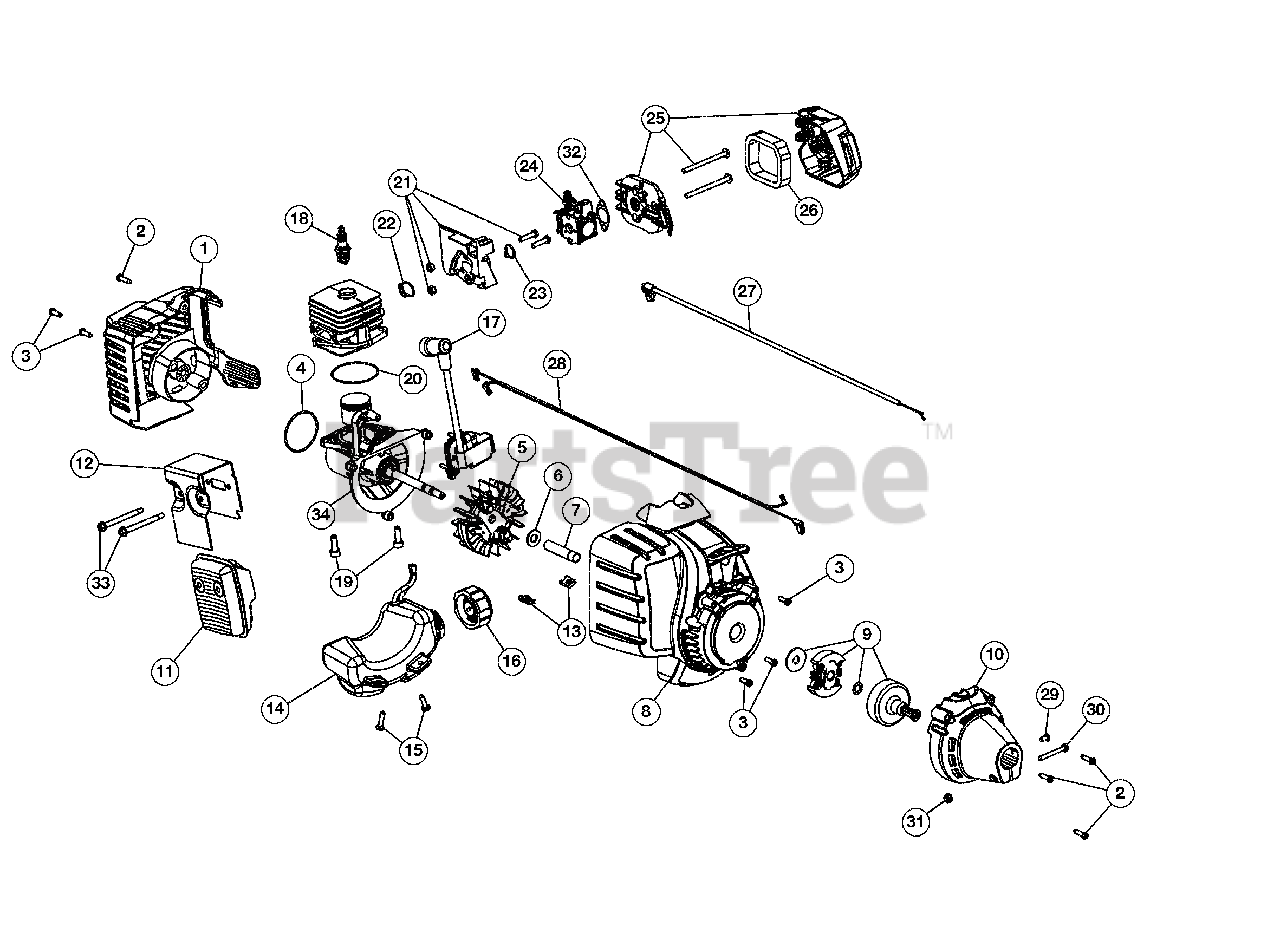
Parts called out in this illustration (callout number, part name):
1	Rear Cover Assembly (Incl. 2 & 3)
2	Cover Screw
3	Housing Screw
4	O-Ring
5	Flywheel Assembly
6	Washer
7	Spacer
8	Starter Housing (Incl. 3 & 13)
9	Clutch Assembly
10	Clutch Cover (Incl. 2)
11	Muffler Assembly (Incl. 12 & 33)
12	Muffler Gasket
13	U-shaped Nut
14	Fuel Tank Assembly (Incl. 15 & 16)
15	Tank Screw
16	Fuel Cap
17	Module Assembly
18	Spark Plug
19	Crankcase Bolt
20	Crankcase O-Ring
21	Insulator Assembly (Incl. 22 & 23)
22	Insulator O-Ring
23	Carburetor O-Ring
24	Carburetor
25	Aircleaner Cover Assembly (Incl. 26)
26	Aircleaner Filter
27	Throttle Cable
28	Lead Wires
29	Anti-rotation Screw
30	Clamp Screw
31	Clamp Nut
32	Air Cleaner Gasket
33	Muffler Screw
34	Short Block Assembly (Incl. 4-7 & 17-20)
